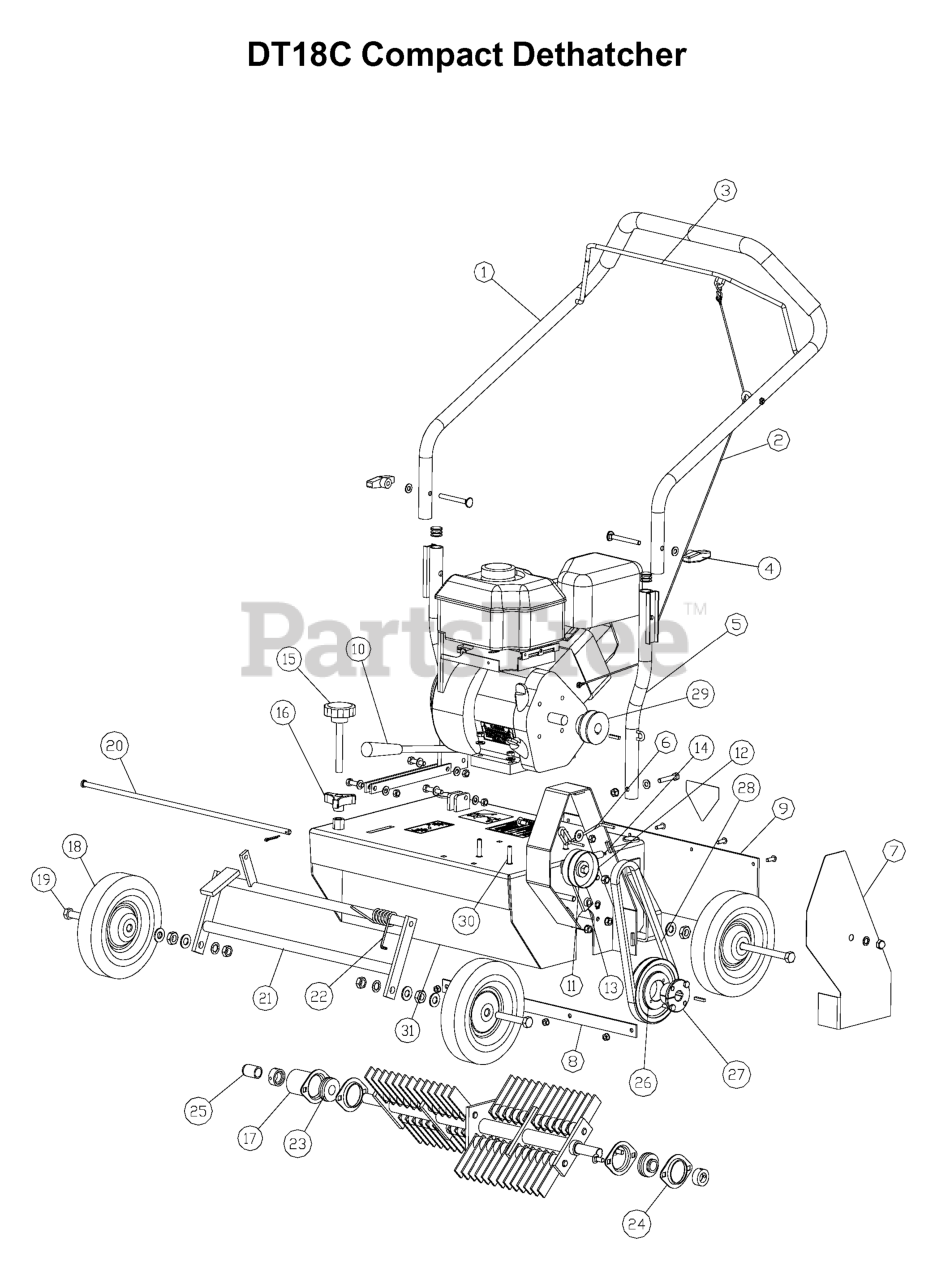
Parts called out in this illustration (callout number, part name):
1	KIT, HANDLE ASSY
2	CLUTCH CABLE
4	BOLT KIT
5	BELT KEEPER KIT
6	BELT GUARD KIT ORN
7	DEFLECTOR KIT
8	DEFLECTOR, NEOPRENE
9	DEPTH LEVER ASSY
10	IDLER ASSY KIT
11	PULLEY
12	MTG ARM, IDLER PULLEY
13	SPRING
14	DEPTH ADJUSTMENT KNOB
15	3-PRONGED LOCK DEPTH
16	ROTOR GUARD
17	WHEEL
18	REAR WHEEL
19	BOLT KIT
20	BOLT KIT
21	WHEEL PLATE KIT
22	LIFT ARM ROD KIT
23	LIFT ARM ASSY OR
24	TORSION SPRING
25	BEARING
26	STAMPING KIT
27	ROTOR CAP
28	V-PULLEY
29	BUSHING KIT
30	V-BELT
31	V-BELT
32	V-PULLEY
33	V-PULLEY
34	ENGINE BOLT KIT
35	DECK COVER KIT
37	KIT, DECAL, DT18
